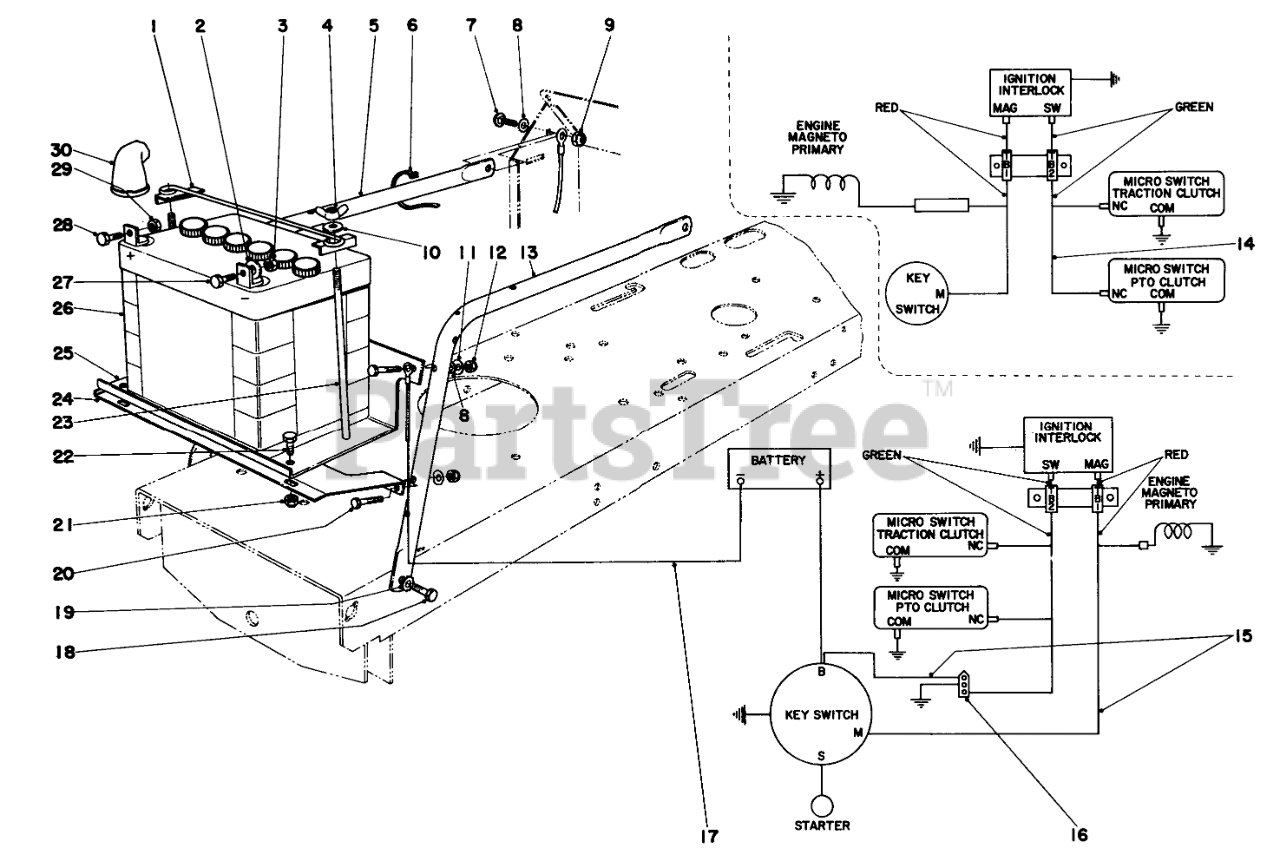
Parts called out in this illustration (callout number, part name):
1	Clamp
2	WASHER-FLAT
3	NUT-HEX
4	WING NUT
5	Support Gas Tank, Right
6	Cable Tie
7	SCREW-CARRIAGE
8	WASHER-LOCK/EXT
9	NUT-LOCK
10	WASHER-FLAT
11	WASHER
12	NUT-LOCK, CONE
13	Support Gas Tank, Left
14	Wire Harness (Model 57131)
15	Wire Harness (Model 57017 Only)
16	Socket Assembly (Model 57017 Only)
17	Wire Assembly
18	SCREW-HH
19	WASHER-LOCK
20	SCREW-HH
21	NUT-LOCK, CONE
22	SCREW-HH
23	BATTERY BOLT
24	Brace Battery Shelf (Model 57228)
25	Shelf, Battery (Model 57228)
26	Battery
27	SCREW-HH
28	SCREW-HH
29	NUT-HEX
30	BATTERY BOOT
